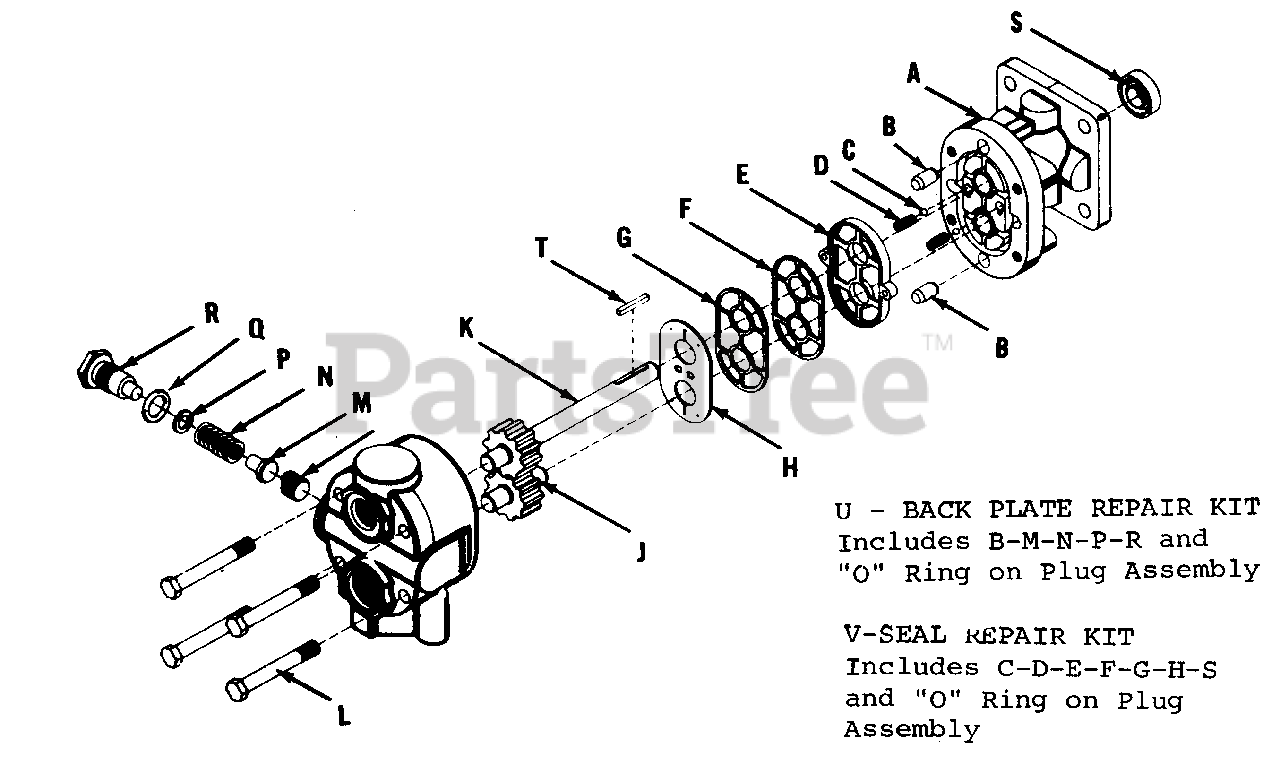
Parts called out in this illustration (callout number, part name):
A	Front Plate Ass'y.
B	Dowel Pin
C	Steel Ball
D	Check Spring
E	Diaphragm Seal
F	Protector Gasket
G	Back-Up Gasket
H	Diaphragm
J	Idler Shaft Ass'y.
K	Drive Shaft Ass'y.
L	Hex. Cap Screw, 1/4"-20 N.C. x 2"
N	Relief Spring
R	Hex. Plug
S	Shaft Seal
U	Back Plate Repair Kit
V	Major Seal Repair Kit
